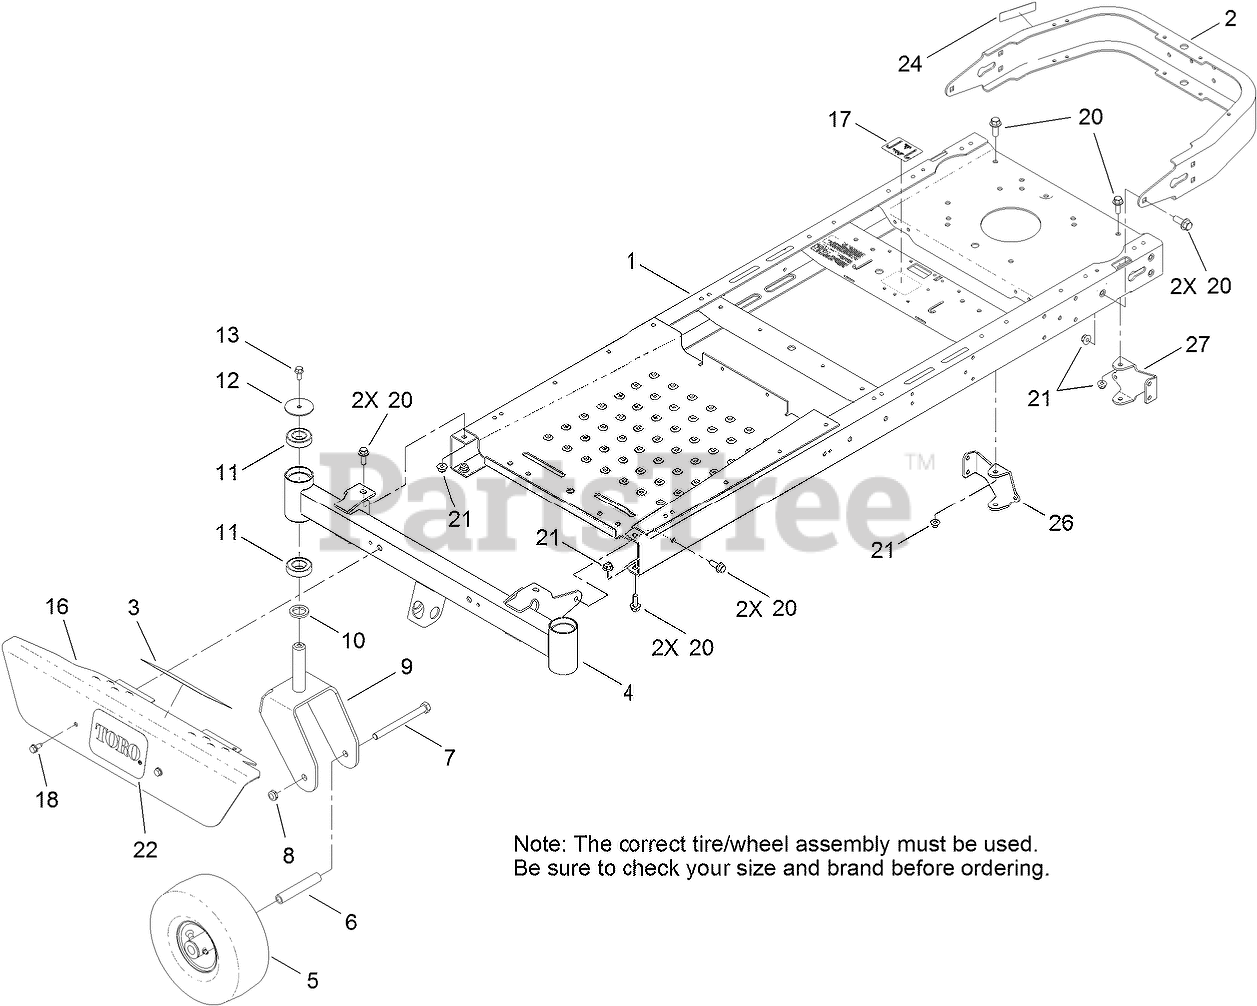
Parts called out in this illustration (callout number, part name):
1	FRAME ASM
2	BUMPER-REAR
3	DECAL-DANGER
4	AXLE-FRONT
5	CASTER WHEEL ASM (Kenda)
5	CASTER WHEEL ASM (CST)
6	BUSHING-SPANNER
7	SCREW-HH
8	NUT-LOCK, NI
9	FORK-CASTER
10	WASHER-THRUST
11	BEARING-BALL
12	WASHER
13	SCREW-HHF
16	FOOTREST
17	DECAL-TRANSPORT
18	SCREW-HWHTF
20	SCREW-HHF
21	NUT-HF, NI
24	DECAL-ARRESTER, SPARK
26	MOUNT-HYDRO, REAR (RH)
27	MOUNT-HYDRO, REAR (LH)
